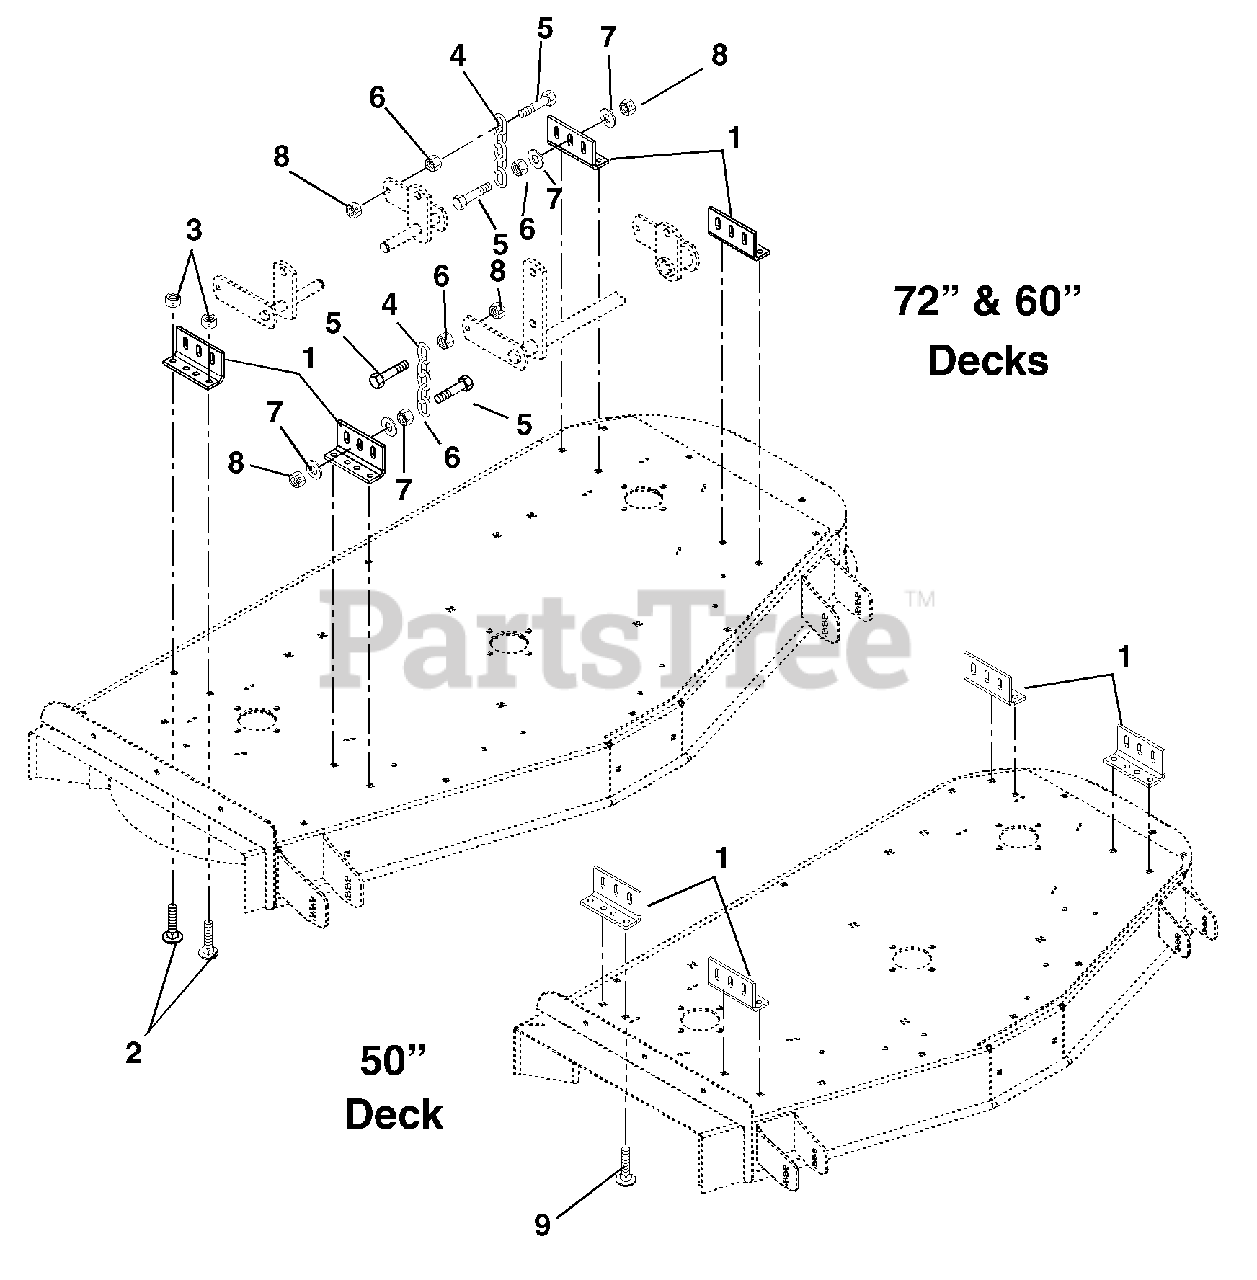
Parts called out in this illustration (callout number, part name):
1	Bracket, Mower Mounting
2	Bolt-Round Head Square Neck .38-16 x 1.25 Grade 2 (60" Deck)
2	Bolt-Round Head Square Neck .38-16 x 1.25 Grade 2 (50" Deck)
3	Nut-Locking-Nylon .38-16
4	Chain, Link
5	Bolt-Hex .38-16 x 1.50 Grade 5
6	Nut-Hex .38-16
7	Washer-Flat-Steel .406 x .812 x .065
8	Nut-Locking-Center .38-16
9	Bolt-Round Head Square Neck .38-16 x 1.50 Grade 2 (50" Deck)
